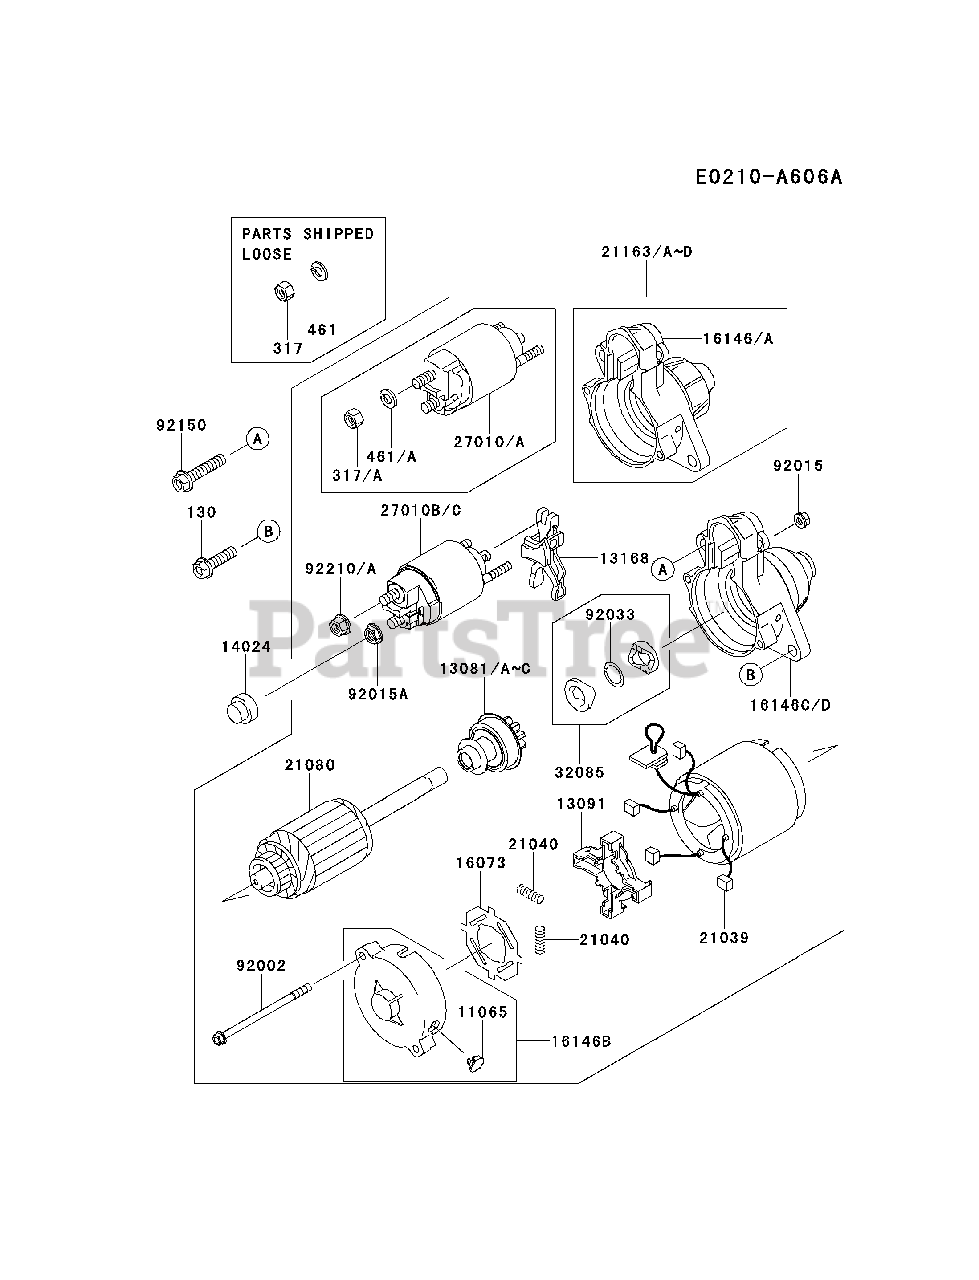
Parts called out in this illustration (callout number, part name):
130	BOLT-FLANGED,8X30
317	NUT-HEX-SMALL,8MM
317A	NUT-HEX-SMALL,8MM
461	WASHER-SPRING,8MM
461A	WASHER-SPRING,8MM
